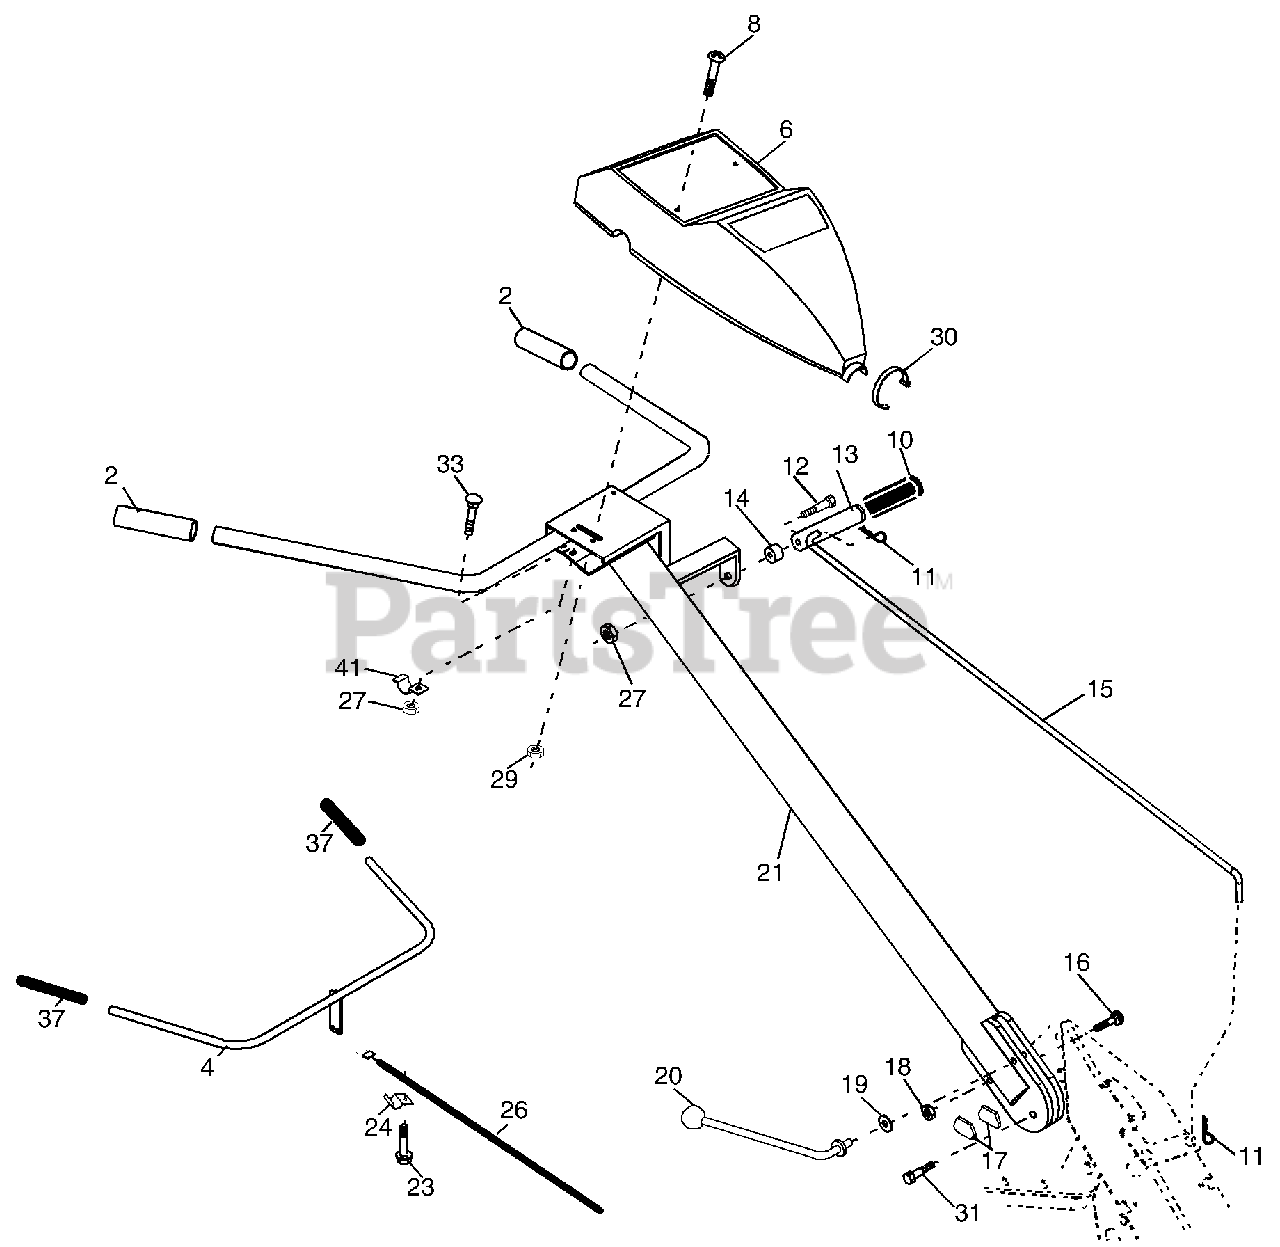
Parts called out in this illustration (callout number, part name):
2	Grip, Handle
4	Bar Assembly, Control
6	Panel, Control
8	Screw, Truss Hd. #10-24 unc x 1/2
10	Grip, Handle
11	Clip, Hairpin
12	Bolt, Shoulder
13	Handle, Shift
14	Grommet, Rubber
15	Rod, Shift
16	Bolt, Carriage 3/8-16 x 1 Gr. 5
17	Lock, Handle
18	Nut, Crownlock 3/8-16 unc
19	Washer 13/32 x 1 x 11 Ga.
20	Lever, Lock, Handle
21	Handle
23	Screw, Hex Washer Hd. Slotted #10-24 x 1/2
26	Cable, Clutch
27	Nut Hex Flange 1/4-20 unc
29	Nut, Keps #10-24 unc
30	Tie, Cable
31	Bolt, Pivot
33	Bolt, Carriage 1/4-20 unc x 1/2
37	Grip, Bar, Control
41	Clamp, Bar, Control
